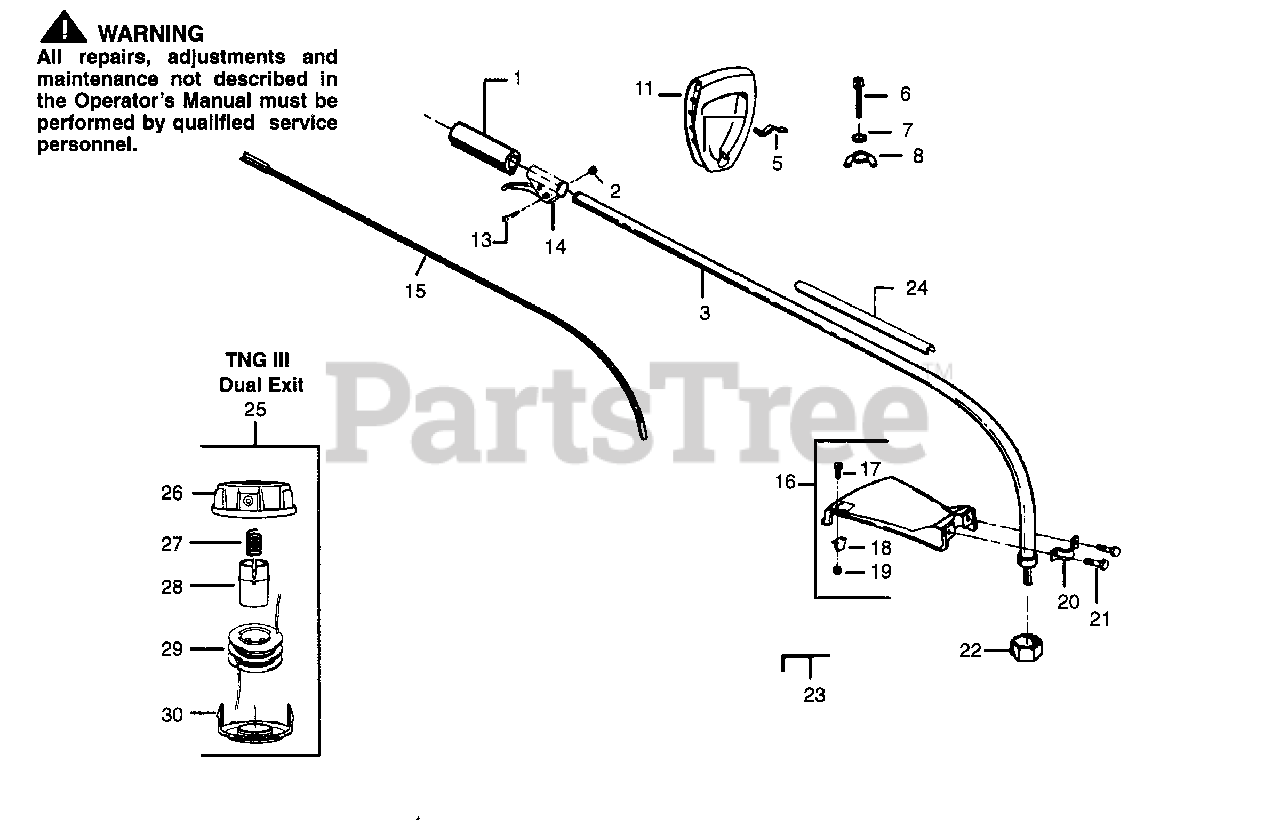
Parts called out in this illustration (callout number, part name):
2	Nut-Throttle Hsg.
3	Drive Shaft Hsg.
11	Handle
13	Screw-Throttle Hsg.
14	Throttle Hsg. Ass'y.
15	Drive Shaft
16	Shield Kit Ass'y. (Inc. 17-19 & 21)
17	Screw-Line Limiter
18	Line Limiter
19	Locknut
20	Shield Bracket
21	Screw-Shield
22	Dust Cup
23	Hex Wrench (5/32)
24	Shaft Warning Decal
25	Cutting Head Ass'y. (5/16" arbor)
26	Hub Ass'y.
28	Release Button
29	Spool w/Line
